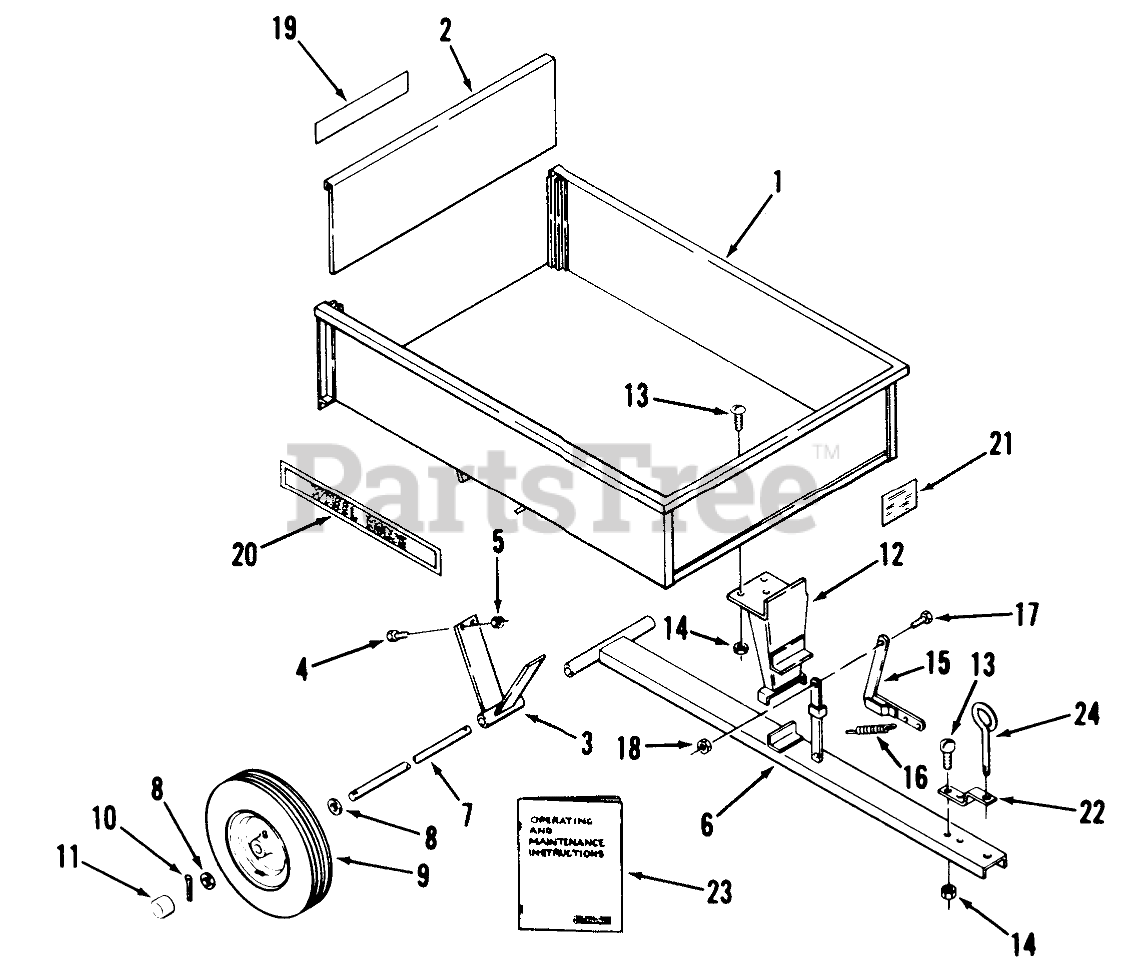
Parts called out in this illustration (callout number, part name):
1	Bed Assembly
2	Rear Gate
3	Axle Holder Assembly
4	BOLT
5	Nut
6	Drawbar Assembly
8	Special Washer
9	Wheel Assembly (4.30-8)
11	HUB CAP
12	Drawbar Spacer Assembly
13	Truss Hd. Bolt 3/8-16 x 3/4
14	Nut
15	Latch Assembly
16	SPRING
17	Bolt
18	Nut
19	DECAL-WHEEL HORSE
20	Decal
21	Decal-Weight Limit
22	Clevis
23	Operating and Maintenance Instructions
24	PIN-TOOL
